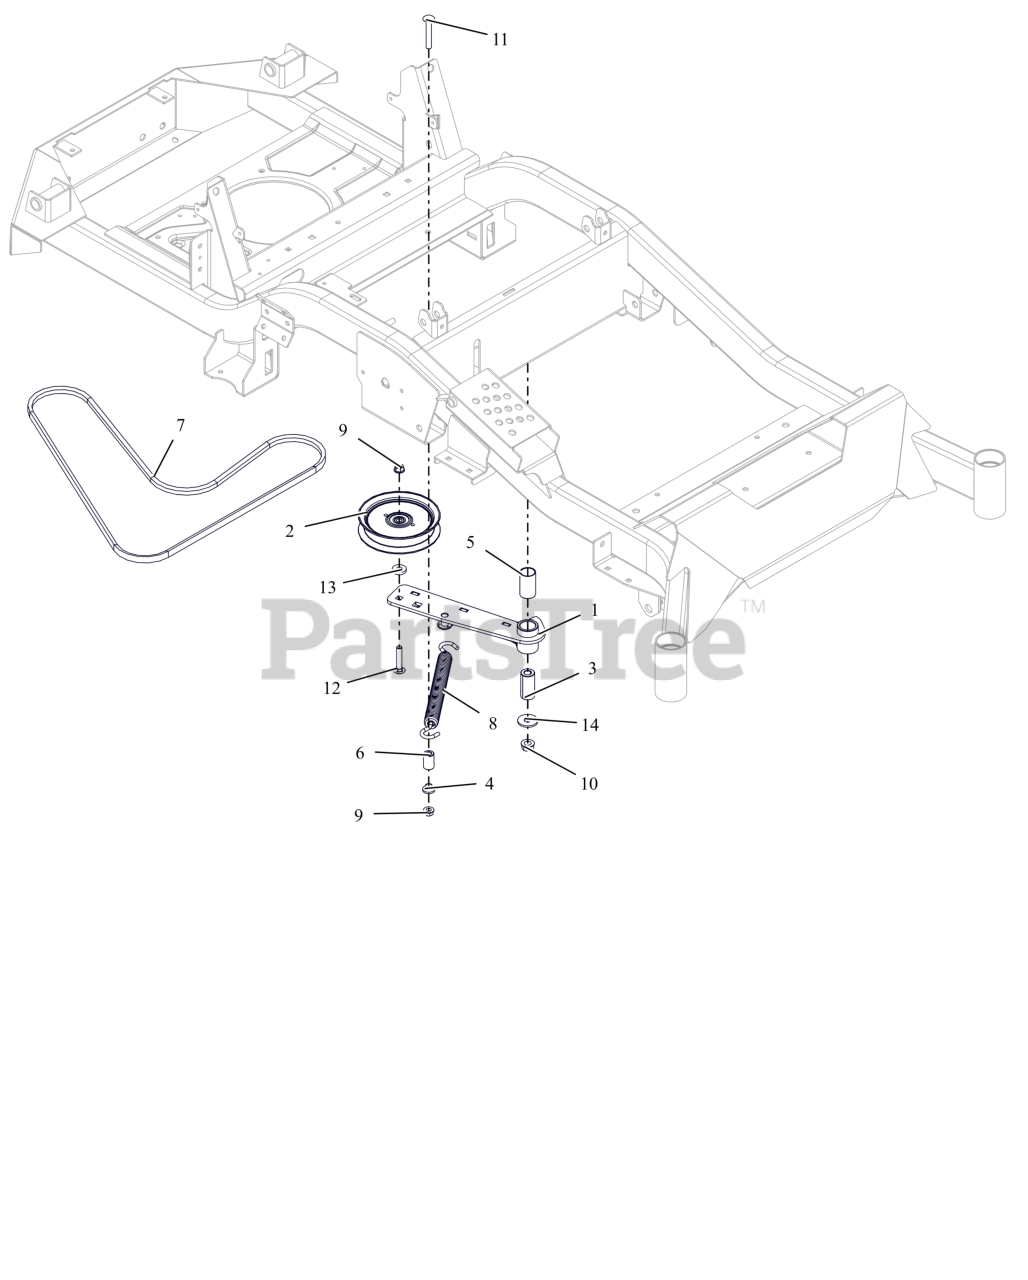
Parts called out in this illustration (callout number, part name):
1	WLDMT, HYDRO DRIVE IDLER ARM
2	IDLER, FLAT 5.00"
3	BSHG, SPCR .502X.997X2.03 PM
4	BSHG-FLG .385X.500X.875X.406
5	BSHG, 1.00X1.125X1.937
6	BUSHING, SLV .380X.750X1.190
7	V-BELT, 4L-WRAPPED
8	SPRING, EXTENSION
9	NUT-LK-TOP-FLG .38-16 ZC120
10	NUT-LK-TOP-FLG .500-13 GF ZCC
11	BLT, RHSSN.38-16X2.50 G5 ZCC
12	BLT, RHSN .38-16X2.00 G5 ZCC
13	WSHR, FLT .406X1.00X.188 ZCC
14	WSHR-FL-STL.511X1.44X.125ZC120
